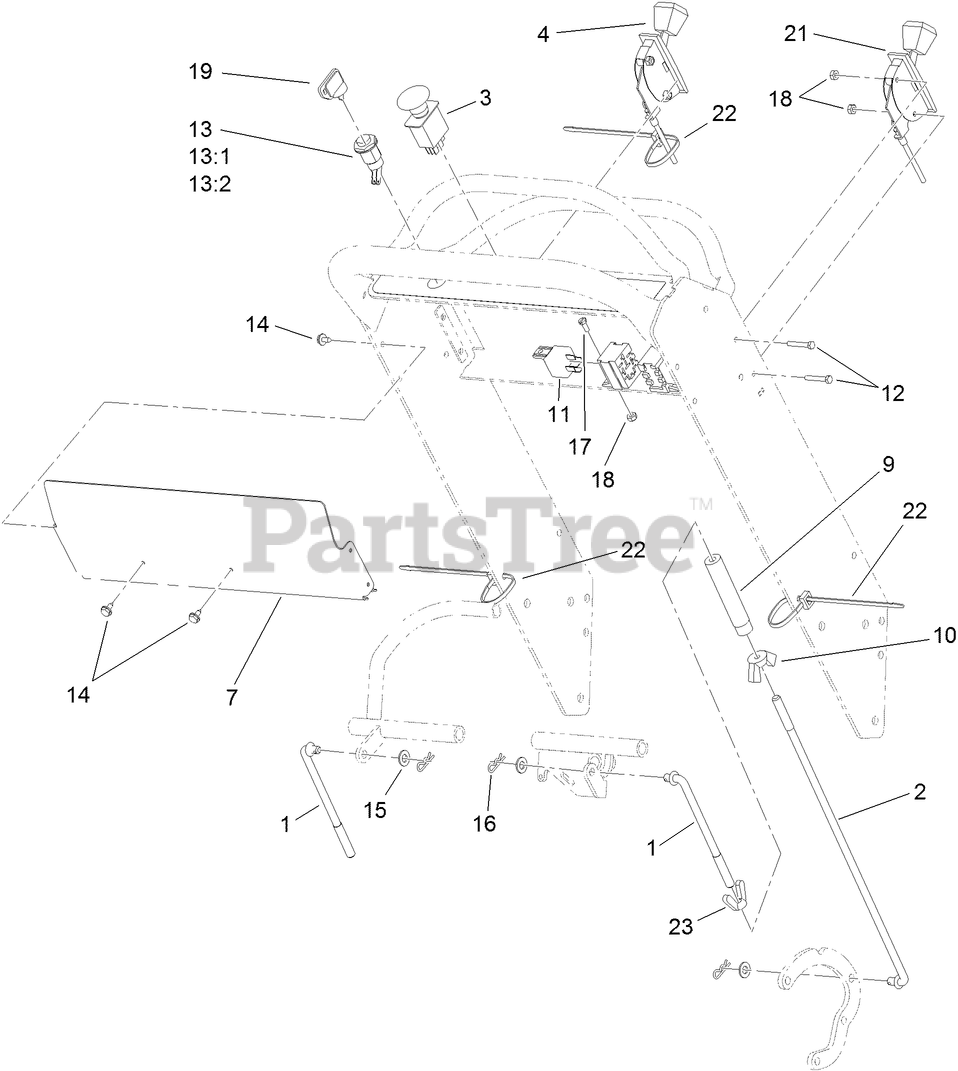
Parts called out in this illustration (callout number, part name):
1	ROD-CONTROL, UPPER
2	ROD-CONTROL, LOWER
3	SWITCH-PTO, ON-ON-(ON)
4	CABLE-THROTTLE
7	COVER-PANEL, CONTROL
9	TURNBUCKLE
10	NUT-WING
12	SCREW-HH
13	SWITCH-ON / OFF
13:1	NUT-HH
13:2	WASHER-TOOTH, INTERNAL
14	SCREW-HWHTF
15	WASHER-PLAIN
16	PIN-COTTER
17	SCREW-SHH
18	NUT-LOCK, NI
19	KEY-IGNITION
21	CABLE-CHOKE
22	TIE-CABLE
23	NUT-WING, LH
